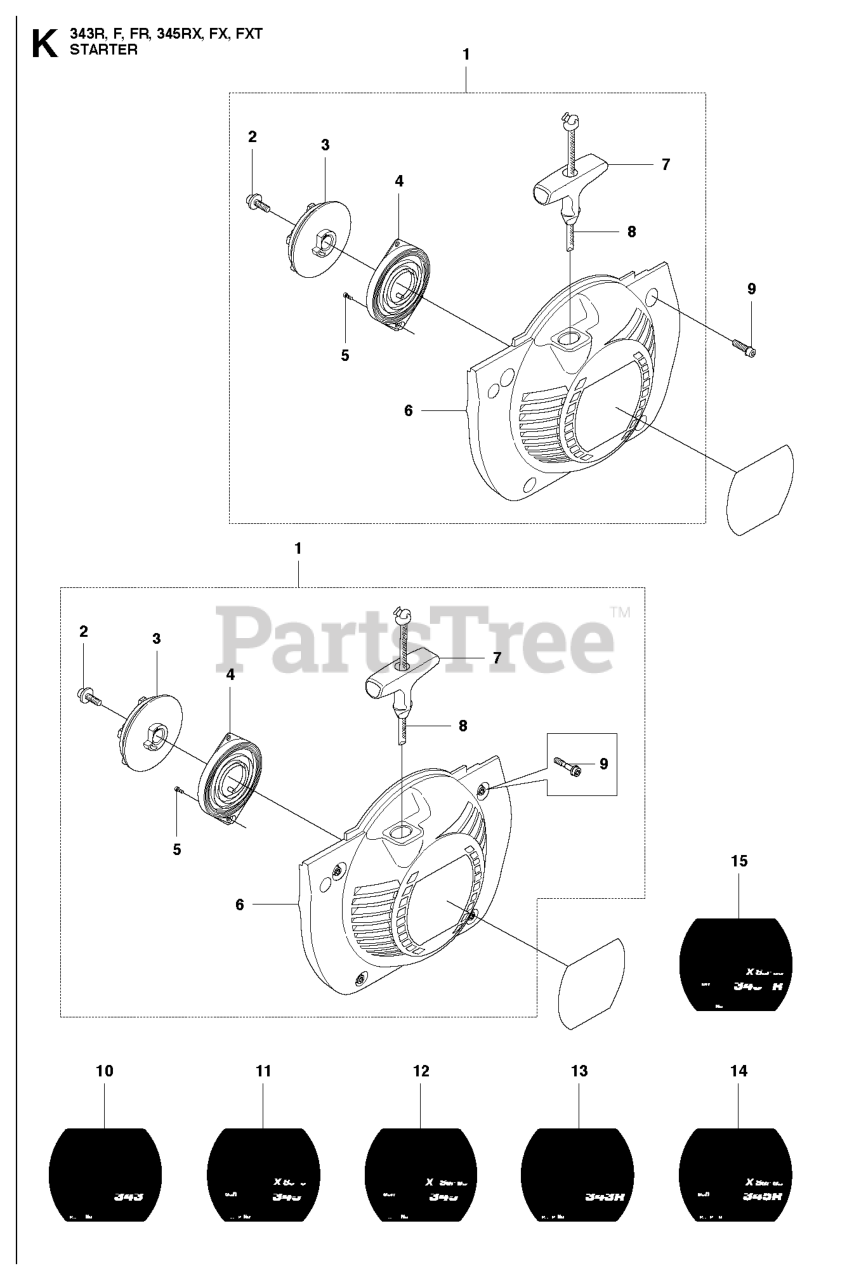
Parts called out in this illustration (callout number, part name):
1	STARTER ASSY.
1	STARTER ASSY
3	STARTER PULLEY
4	RECOIL SPRING
6	STARTER DEVICE
7	STARTER HANDLE
8	STARTER ROPE
9	SCREW IHSCFMO
9	SCREW IHSCFM
10	LABEL STARTAP.343F
11	DECAL
12	LABEL STARTAP.345FXT
13	LABEL STARTAP.343R
14	DECAL
15	LABEL STARTAP.343FR
